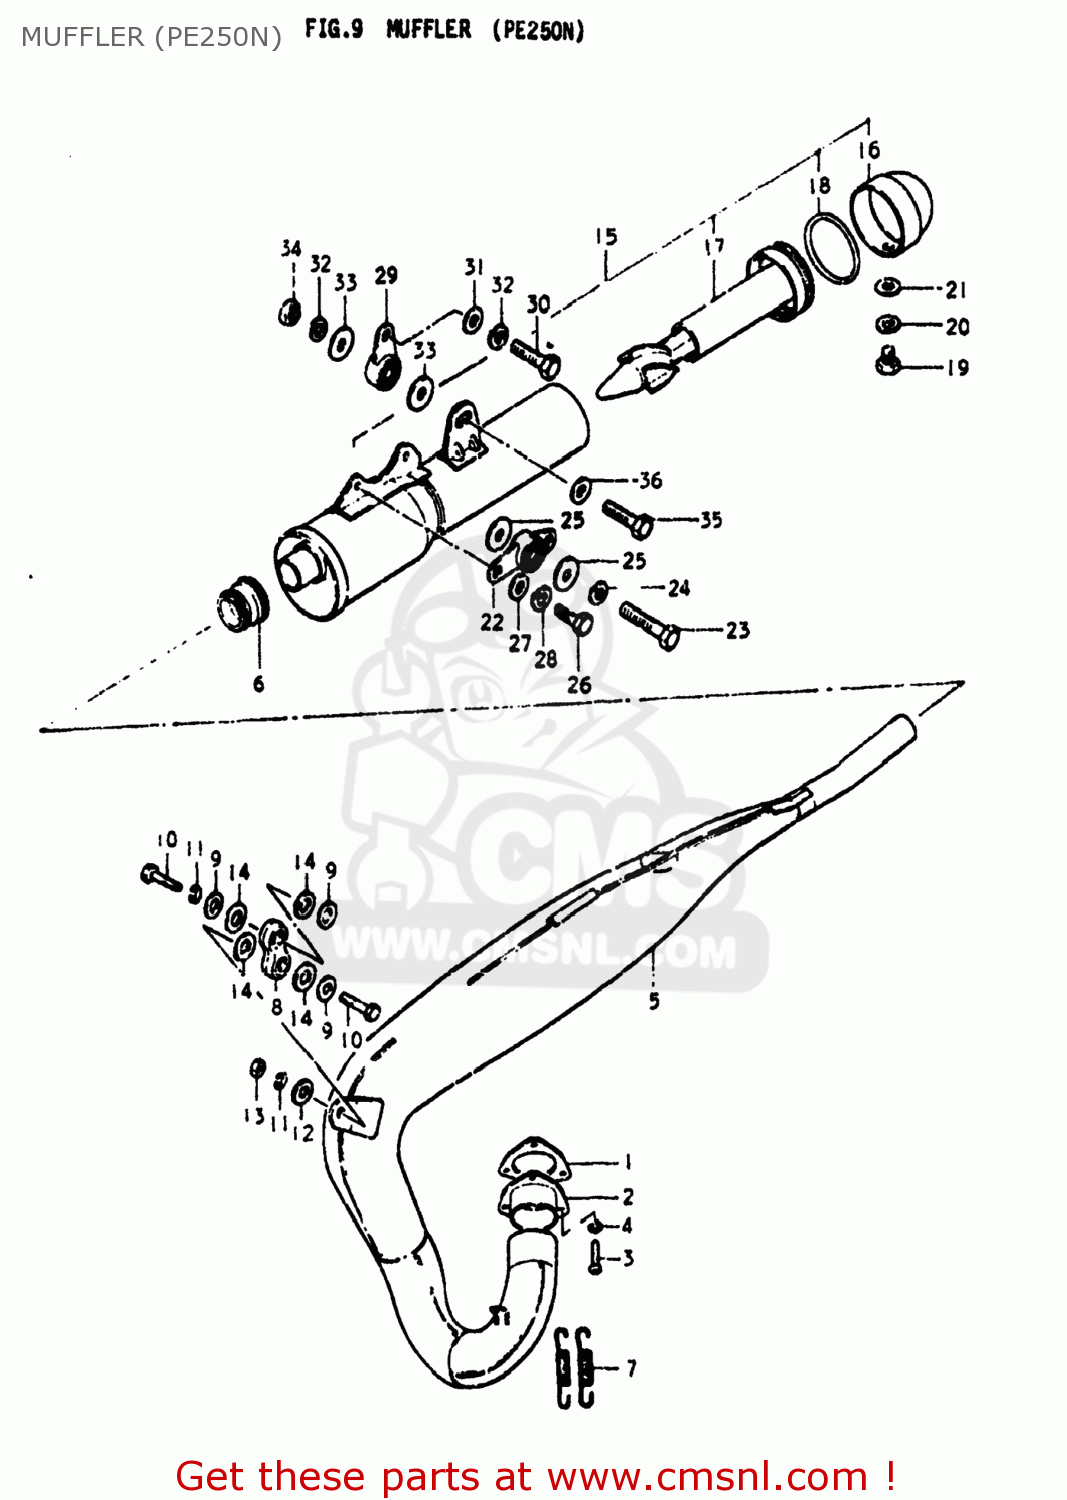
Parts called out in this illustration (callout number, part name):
1	GASKET,EXHAUST PIPE (MCA)
2	FLANGE,EXHAUST PIPE
3	SCREW
4	LOCK WASHER
5	BODY,MUFFLER
6	CONNECTOR,MUFFLER
7	SPRING
8	DAMPER,MUFFLER
9	WASHER
10	BOLT
11	LOCK WASHER
12	WASHER
13	NUT
14	WASHER(13X28X1.6)
15	MUFFLER ASSEMBLY,SECOND
16	COVER,SECOND MUFFLER TAIL
17	TUBE,MUFFLER CLEAN OUT
18	O-RING (D:3.5 ID:54.4)
19	SCREW(6X8)
20	LOCK WASHER
21	WASHER
22	DAMPER,MUFFLER SUPPORT
23	BOLT 8X45
24	LOCK WASHER
25	WASHER (8.5X29X1.6)
26	BOLT, UPPER
27	WASHER
28	LOCK WASHER
29	DAMPER,MUFFLER SUPPORT
30	BOLT
31	WASHER
32	LOCK WASHER
33	WASHER (8.5X29X1.6)
34	NUT
35	BOLT,8X35
36	WASHER
